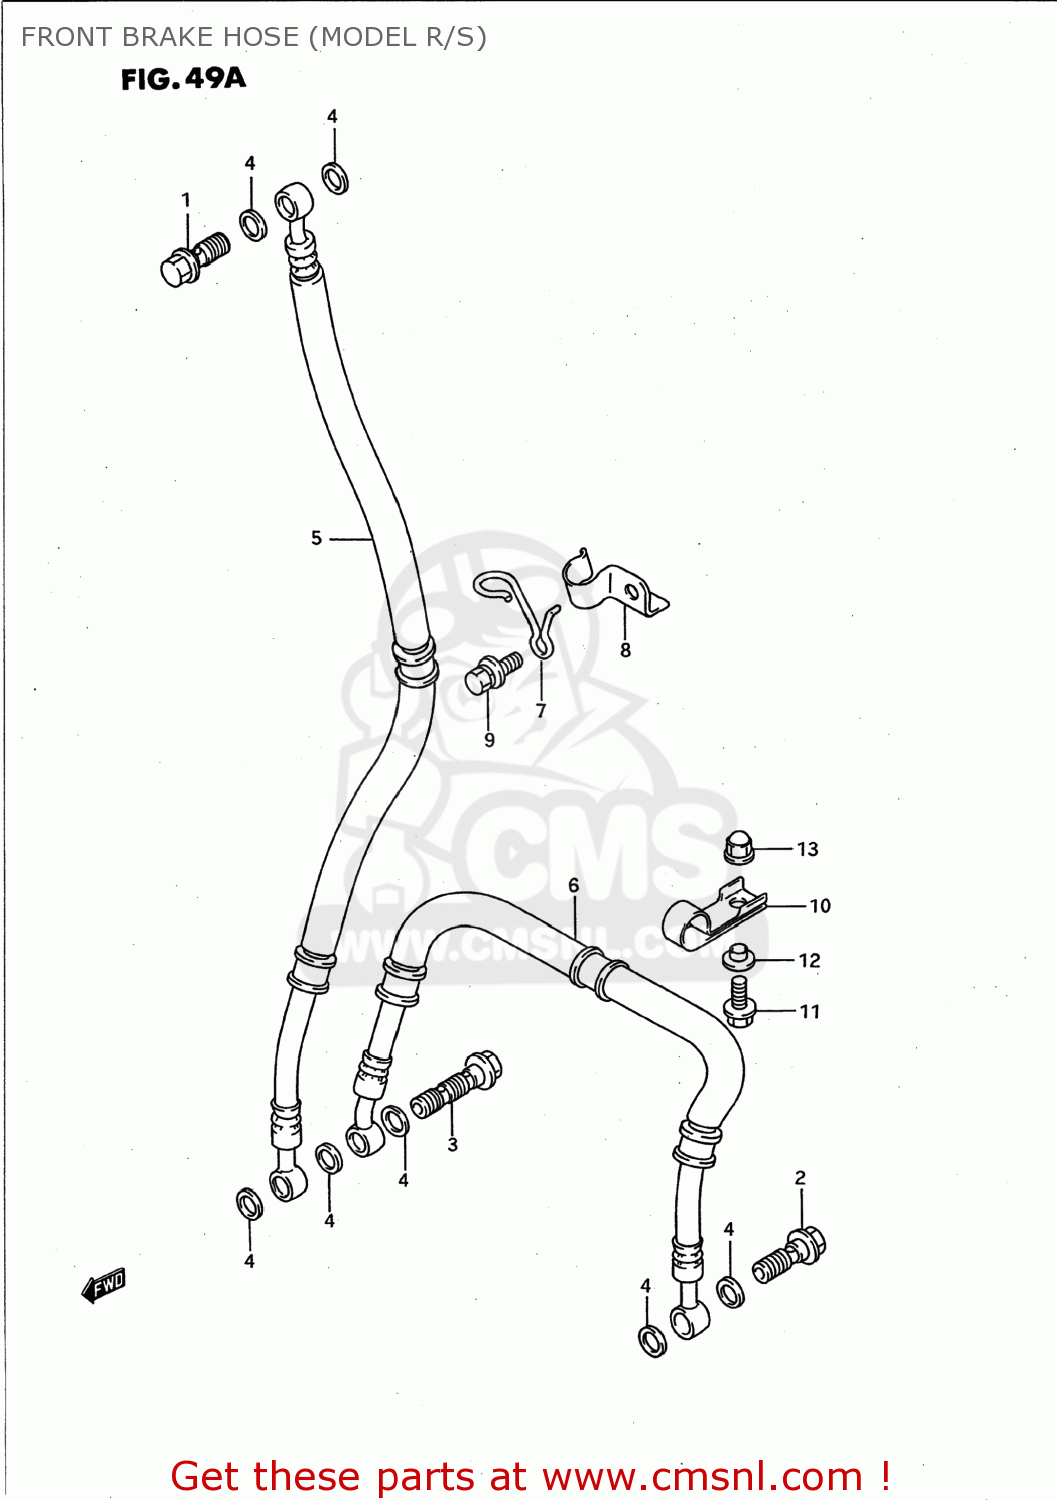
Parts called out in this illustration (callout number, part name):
1	BOLT UNION
2	BOLT UNION
3	BOLT UNION
4	WASHER(10X15X1.5)
5	HOSE,FR BRAKE NO.1
6	HOSE,FR BRAKE NO.2
7	GUIDE,FR BRAKE HOSE
8	CLAMP,FR BRAKE HOSE UPR
9	BOLT
10	CLAMP,FR BRAKE HOSE NO.2
11	BOLT
12	WASHER
13	NUT
